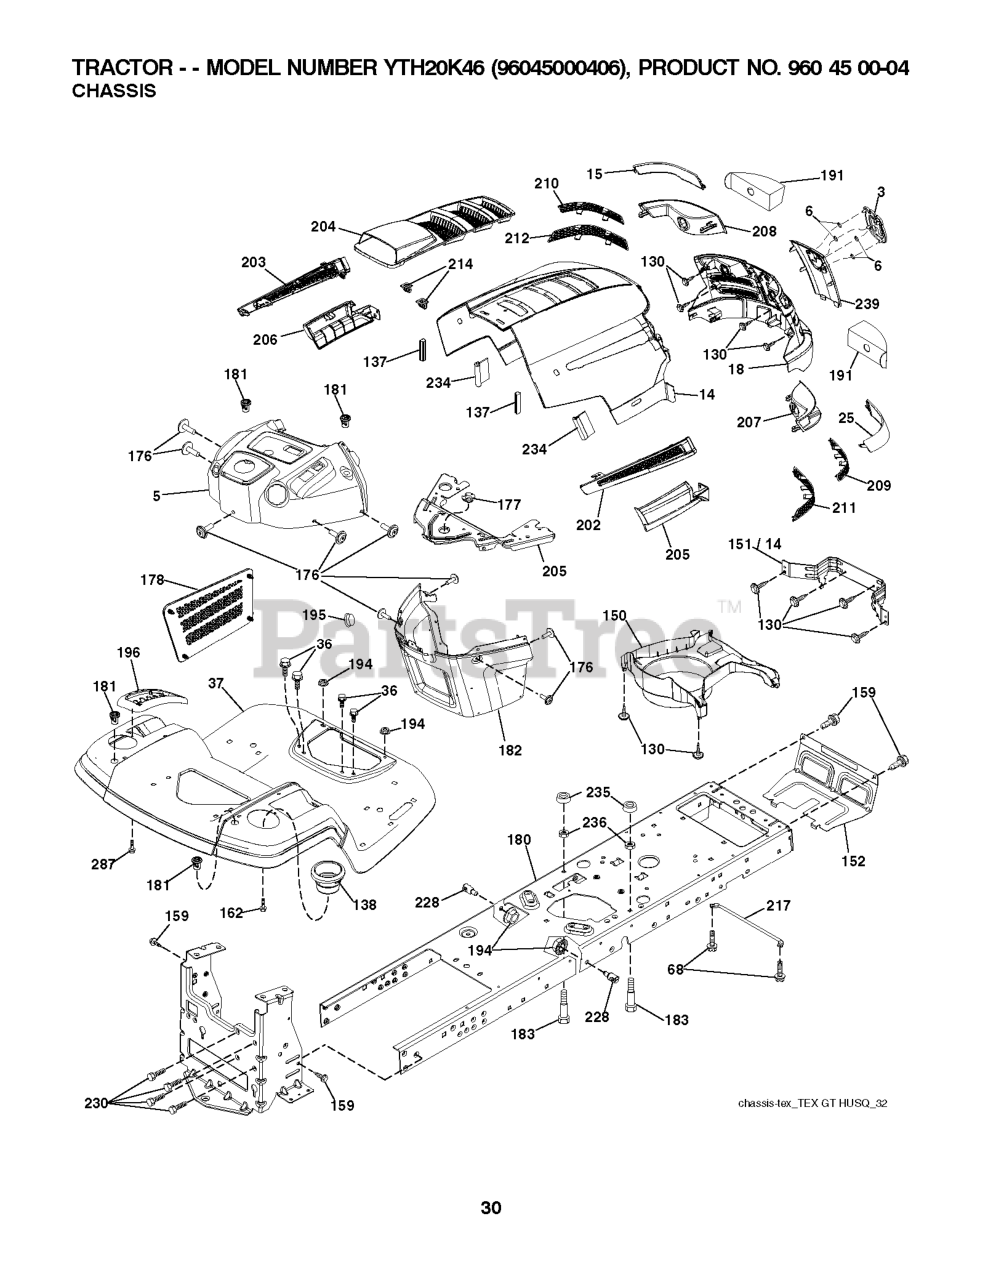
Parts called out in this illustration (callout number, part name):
2	DRAWBAR.1PC.NSTL
3	RP LOGO
14	HOOD
15	LENS.LH.TEX.GT.HUSQ.CL
18	GRILL.ASM.HUSQ.TG/CRD.W/TRIM
25	LENS.RH.TEX.GT.HUSQ.CL
36	SCREW 5/16"
37	FENDER
68	Screw 5/16-18 x 1/2 Hex, Self Tapping 5/16-18 x 1/2
130	SCREW.#10 X 0.750.BOS
137	BUMPER DASH
138	CUPHOLDER.TL.TEX.418
150	AIR.DUCT.TEXGT.HUSQ.SV
151	HOOD
152	SHIELD.BROWNING/DEBRIS
159	SCREW, 3/8-16X3/4
162	SCREW.HI-LO.CONSOLE
175	PLATE.CROSSMEMBER.HUSQ
176	SCREW.#10-24X5/8.RN.QU
177	BUSHING, STEERING
178	CARGO.ASM.NET.TXGT.W/C
180	CHASSIS.STAMPING.LT/GT
181	BUSHING.MNT.FEND.CRGO.
182	DASH.LOWER.COMMON.12V.ADAPTOR
183	BOLT.5/16-18X1-1/4 FULL.THREAD
194	NUT LOCK HEX FLANGE 5/16-18
195	PLUG.HOLE.DASH.LOWER.12V.BLK
196	RP CONSOLE.ASM.DECKLFT.GR/RBT.
202	VENT.SIDE.HOOD.HUSQ.RH.GREY
203	VENT.SIDE.HOOD.HUSQ.LH.GRAY
204	HOOD VENT
205	SKIRT.HOOD.SIDE.HUSQ.RH.GREY
206	SKIRT.HOOD.SIDE.HUSQ.LH.GREY
207	BEZEL.RH.TEX.GT.HUSQ
208	BEZEL.LH.TEX.GT.HUSQ
209	INSERT.HEX.GRILL.HUSQ.GREY
210	INSERT.HEX.GRILL.HUSQ.
211	INSERT.HEX.GRILL.HUSQ.
212	INSERT.HEX.GRILL.HUSQ.
214	CLIP.RETAINER.TINNER.
217	ROD.PIVOT.HOOD
228	STUD.FASTNER.W/ANTI-ROTATE
230	SHOULDER BOLT 5/16-18TT
234	BUMPER.HOOD.TEX.HUSQVARNA
235	SPACER FENDER
236	NUT.CENTERLOCK.5/16-
238	TRIM.HUSQ.TG/CRD.SERVICE
239	NUT PUSH M
287	SCREW 1/4X20
